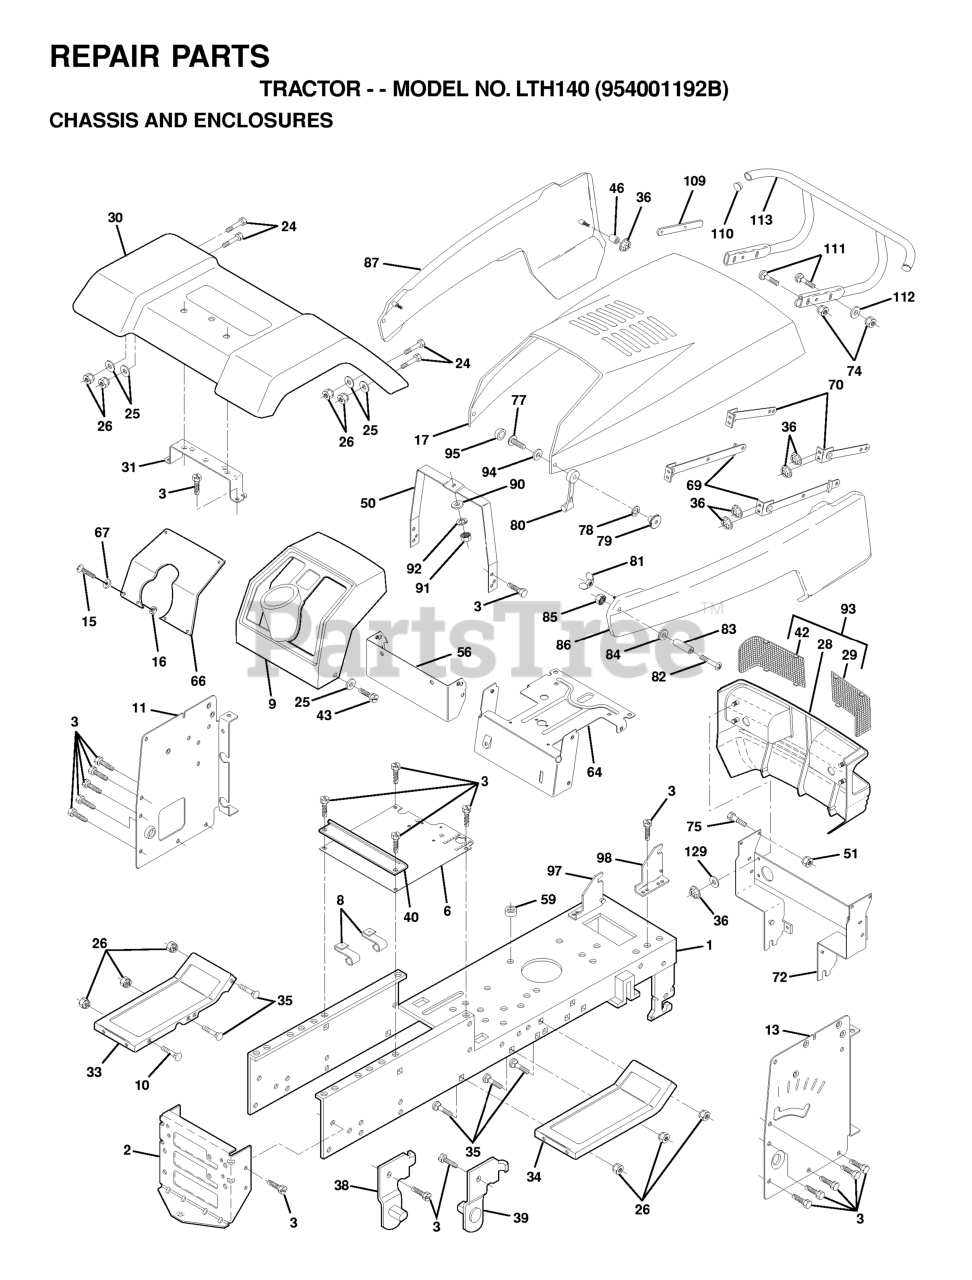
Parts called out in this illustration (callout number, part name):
1	CHASSIS WELD 11GA.95
2	STRETCH DRAWBAR
3	SCREW
6	SADDLE LT FENDER
8	CLIP,INSULATOR
10	BOLT D
11	PANEL DASH LT
13	PANEL DASH RH
15	Screw, Machine, Truss Head 5/16-18 UNC x 3/4
16	NUT
17	HOOD.HUSQVARNA.ORANGE
25	WASHER
26	NUT
28	GRILL
29	LENS RH
30	FENDER
31	BRACKET.SUPPORT.FENDER
33	FOOT REST LH
34	FOOTREST RH
36	PAL NUT LT
38	BRACKET LH PIVOT
39	BRACKET RH PIVOT
41	PLATE
42	LENS LH
43	SCREW GTV
50	DASH SUPT YP
51	LOCKNUT.NYLOC.1/4-20
56	DASH EXT PNT
59	SNAP BUSHING T
60	Bolt - Rd. Hd. Sq. Neckiage 3/8 16 x 3/4
61	Washer 1 17/32 X 7/8 X 16 Ga
64	DASH LOWER YT
66	DASH PLATE
67	WASHER
69	STRAP ASSY LT
70	STRAP ASSY LT
72	SUPT, ASS'Y GRILL
75	BOLT T
77	SCREW
78	LOCKWASHER #10
79	WELDNUT
80	LATCH.HOOD.
81	NUT.WING.LCK.NYL.NOTCH.1/4-20
82	RP SCREW
85	NUT **
86	PANEL SIDE RH
87	PANEL SIDE LH
91	NUT
92	LOCKWASHER
93	GRILL
95	SNAP CAP LT
97	SUPPORT RH YTH
98	SUPPORT LH YTH
109	BRACKET BUMPER
110	PLUG PLASTIC
111	BOLT.3/8-14X1.25
112	WASHER
113	BUMPER ASSY
